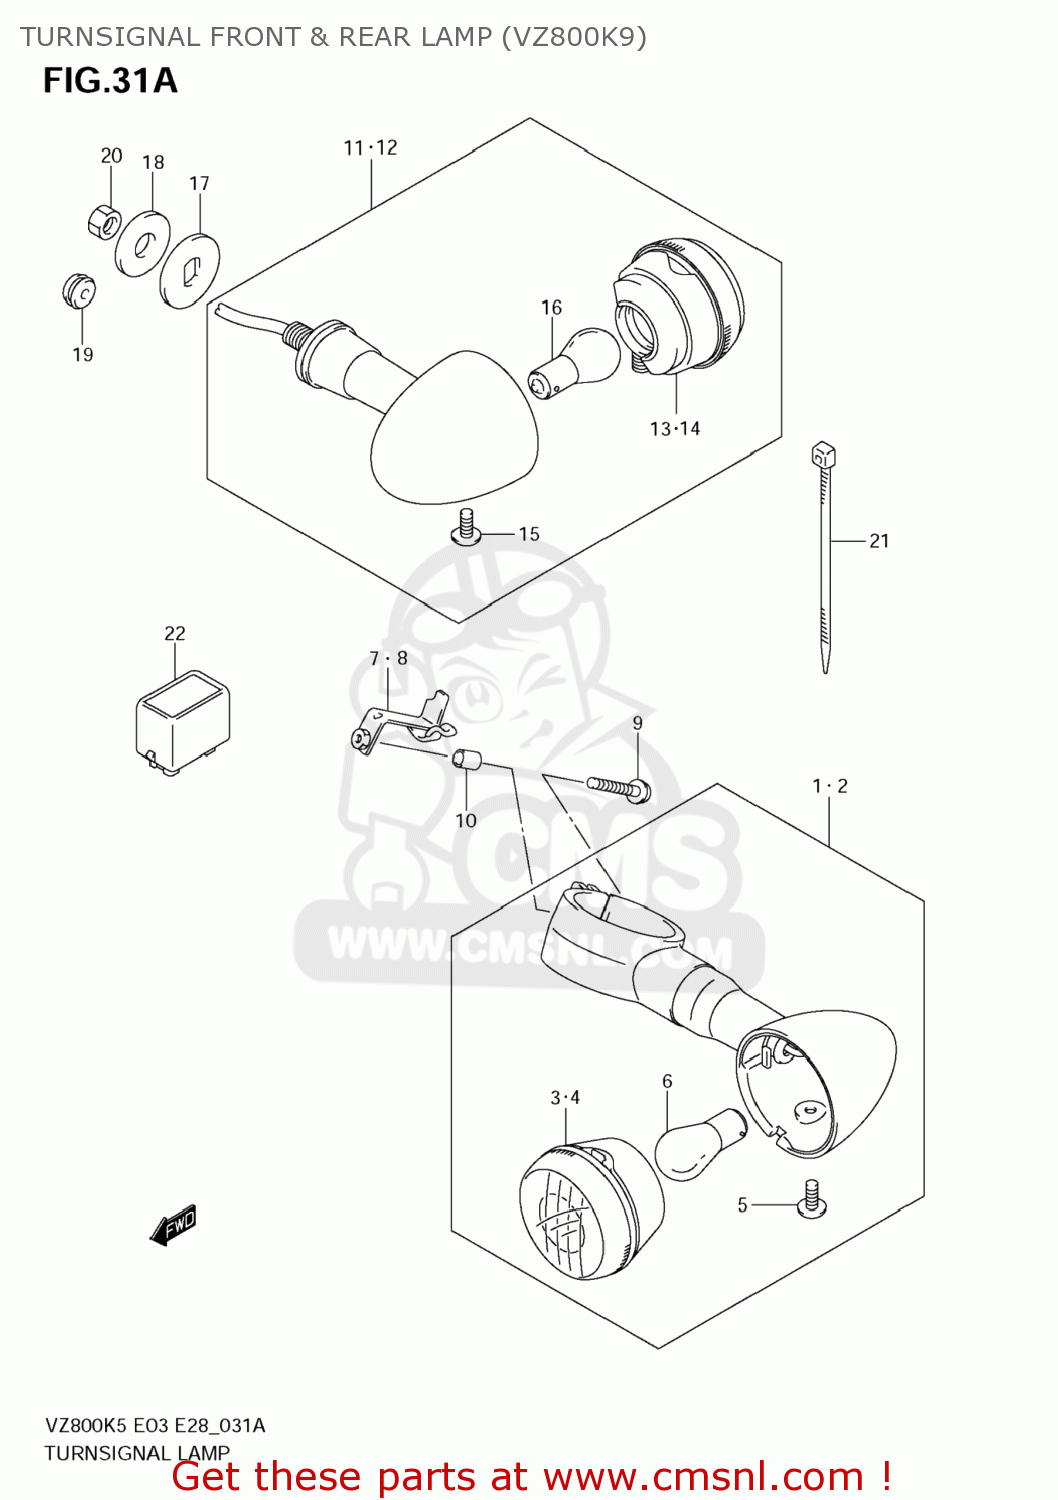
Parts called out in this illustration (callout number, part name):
1	LAMP ASSY,FR TURN SIGNAL,R
2	LAMP ASSY,FR TURN SIGNAL,L
3	LENS
4	LENS
5	SCREW(4X10)
6	BULB(12V21/5W)
7	BRACKET,FR TURNSIGNAL,R
8	BRACKET,FR TURNSIGNAL,L
9	SCREW(6X25)
10	SPACER(6.4X9.2X12)
11	LAMP ASSY,RR TURNSIGNAL,R
12	LAMP ASSY,RR TURNSIGNAL,L
13	LENS
14	LENS
15	SCREW(4X10)
16	BULB(12V21W)
17	SPACER,RR TURNSIGNAL
18	WASHER(10.5X30X2.3)
19	GROMMET
20	NUT
21	CLAMP(L:145)
22	RELAY ASSY,TURNSIGNAL LAMP
